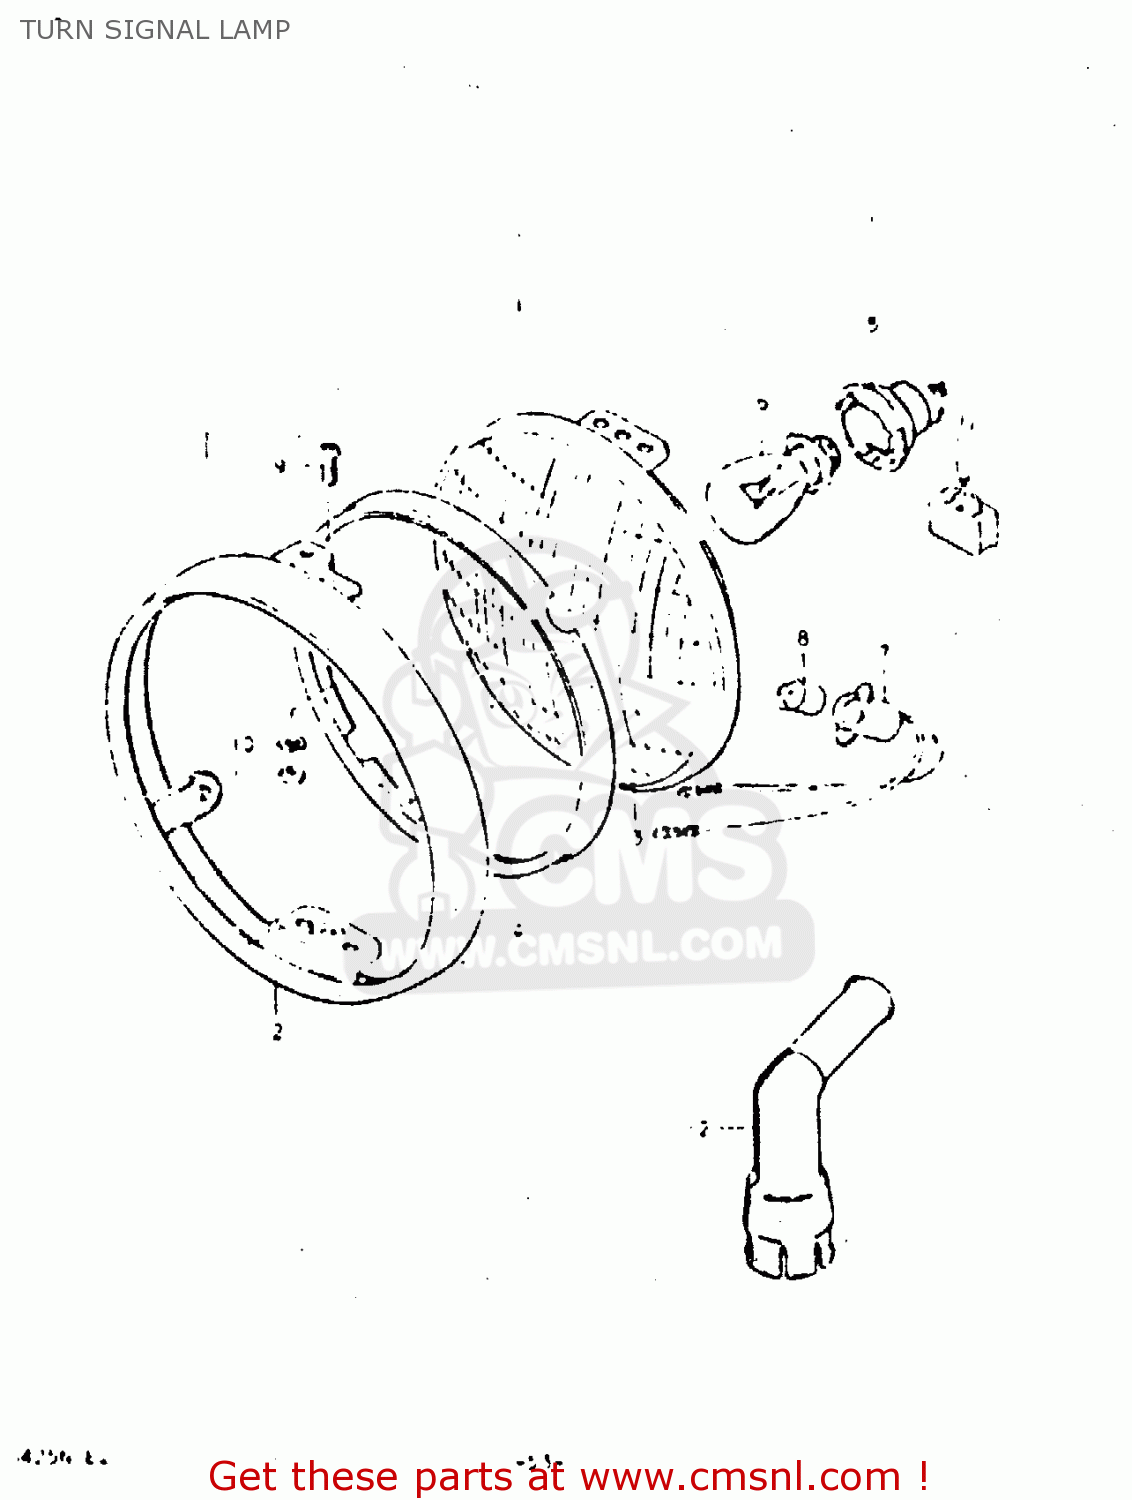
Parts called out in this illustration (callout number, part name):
1	LAMP ASSEMBLY,FRONT TURN SIGNAL
2	LENS
3	GASKET (NAS)
4	BULB(12V23W,STANLEY,A4577A)
5	SCREW
6	GASKET (NAS)
7	CUSHION
8	CUSHION
9	WASHER
10	LOCK WASHER
11	NUT
12	LAMP ASSEMBLY,REAR TURN SIGNAL
13	LENS
14	GASKET (NAS)
15	BULB(12V23W,STANLEY,A4577A)
16	SCREW
17	GASKET (NAS)
18	CUSHION
19	SPACER,RR TURNSIGNAL LAMP
20	WASHER
21	LOCK WASHER
22	NUT
23	BRACKET,TURN SIGNAL
24	LEAD WIRE,EARTH
25	RELAY,TURN SIGNAL
